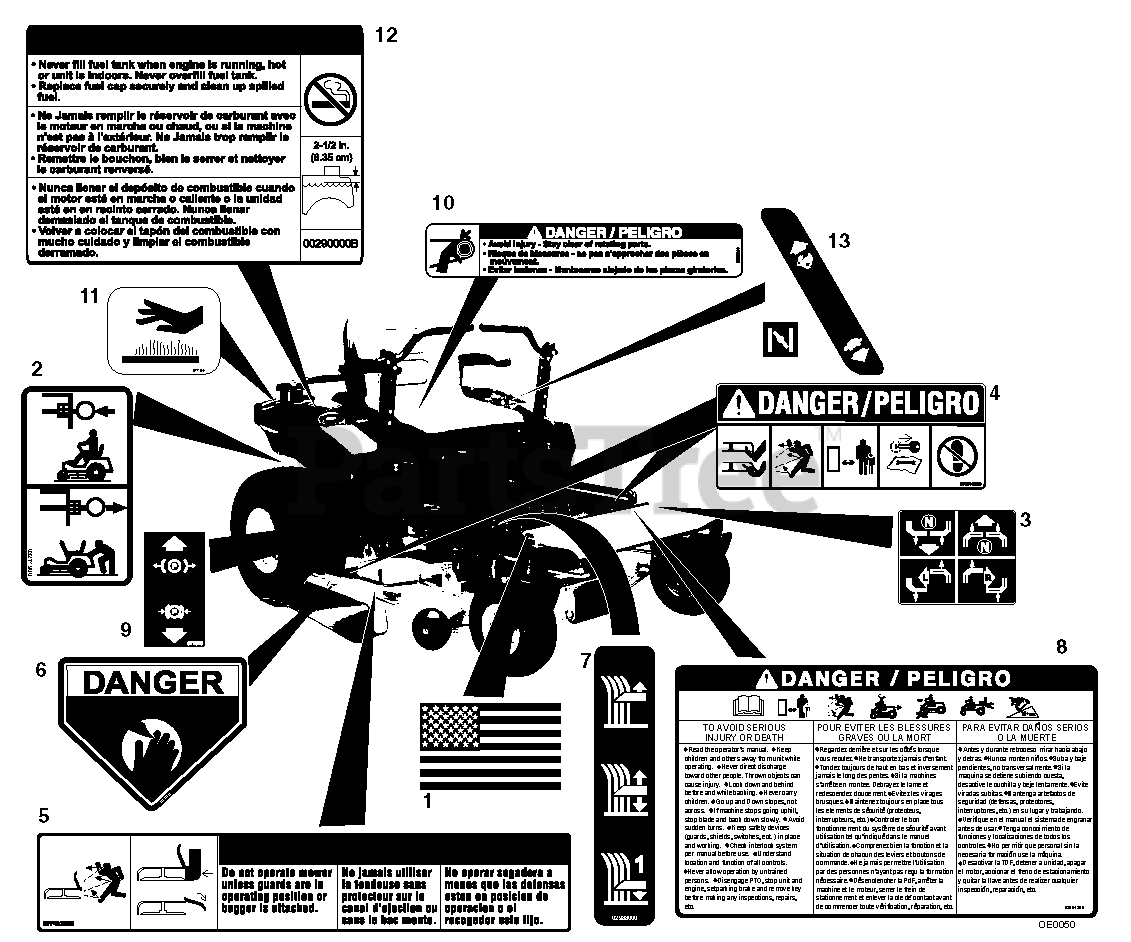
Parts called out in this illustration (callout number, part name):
1	Decal, American Flag
2	Decal, Transmission Disconnect
3	Decal, Instructional Steering
4	Decal, Mower Pan Head Danger
5	Decal, Warning
6	Decal, CPSC Danger
7	Decal, Cut Height
8	Decal, Bilingual Danger
9	Decal, Parking Brake Lever
10	Decal, Danger
11	Decal, Hot Surface
12	Decal, Fuel Warning
13	Decal, Control
